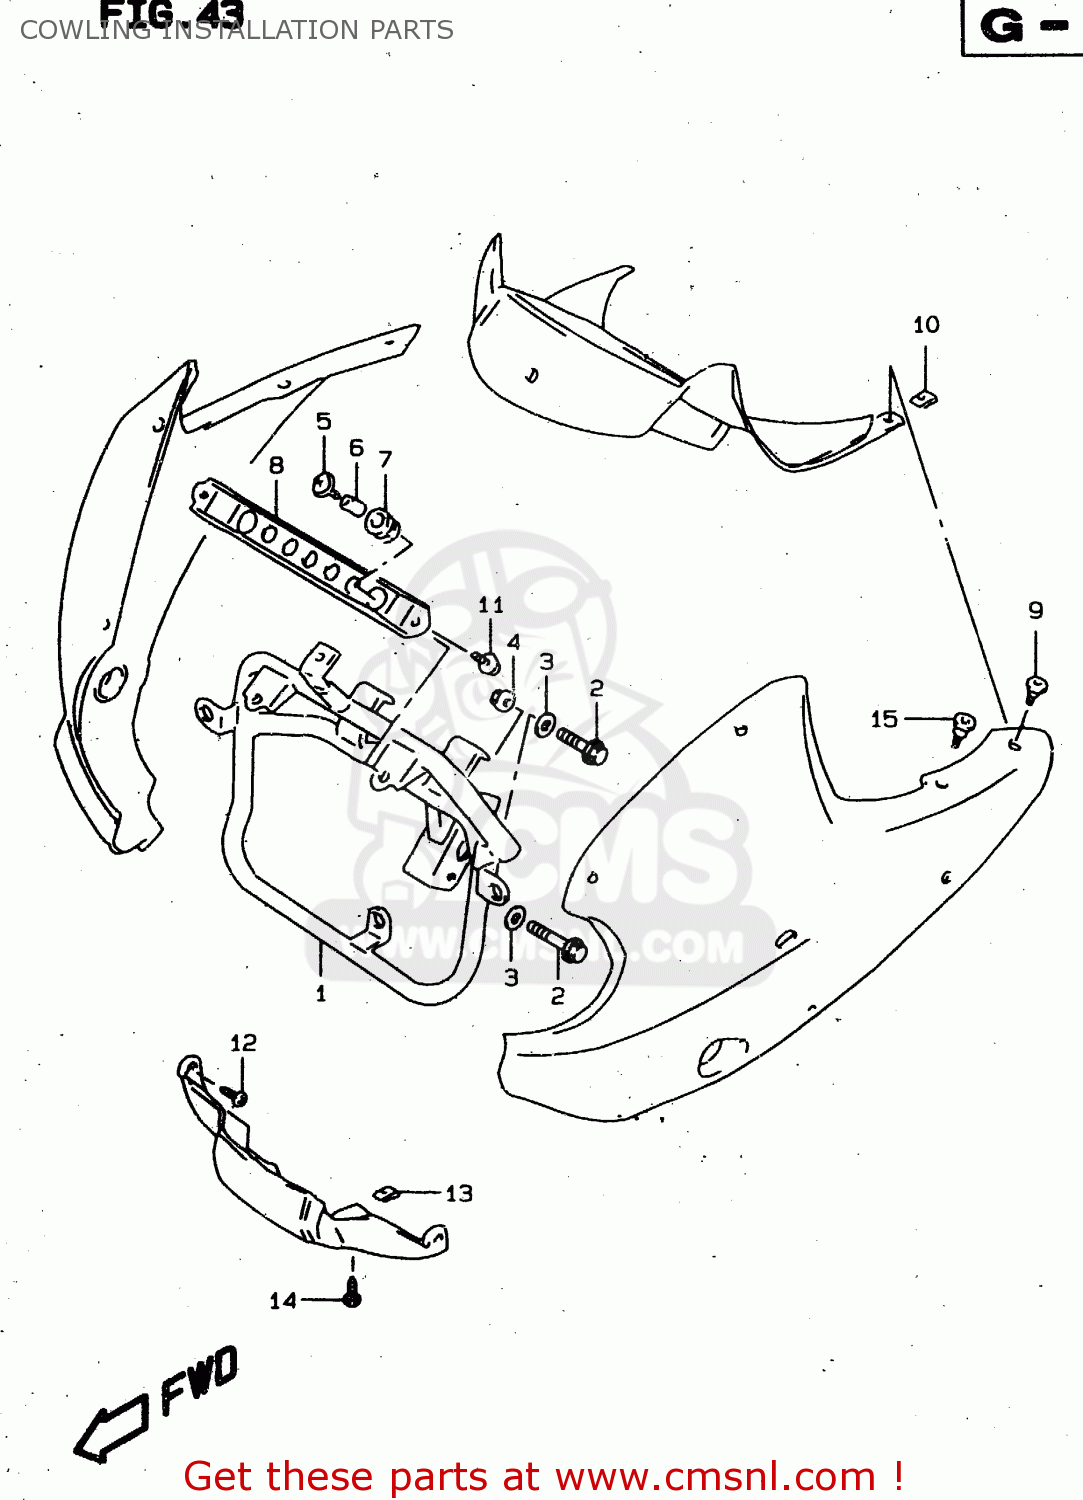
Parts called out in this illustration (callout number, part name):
1	BRACE,COWLING
2	BOLT 8X45
3	WASHER
4	NUT
5	SCREW (6X20) WITH WASHER
6	SPACER(6.5X9X6.7)
7	CUSHION
8	BRACKET,COWLING UPR
9	SCREW(5X16)
10	NUT,HEADLAMP HOUSING,UPPER
11	SCREW 5X12
12	SCREW
13	NUT
14	SCREW
15	SCREW(5X16)
